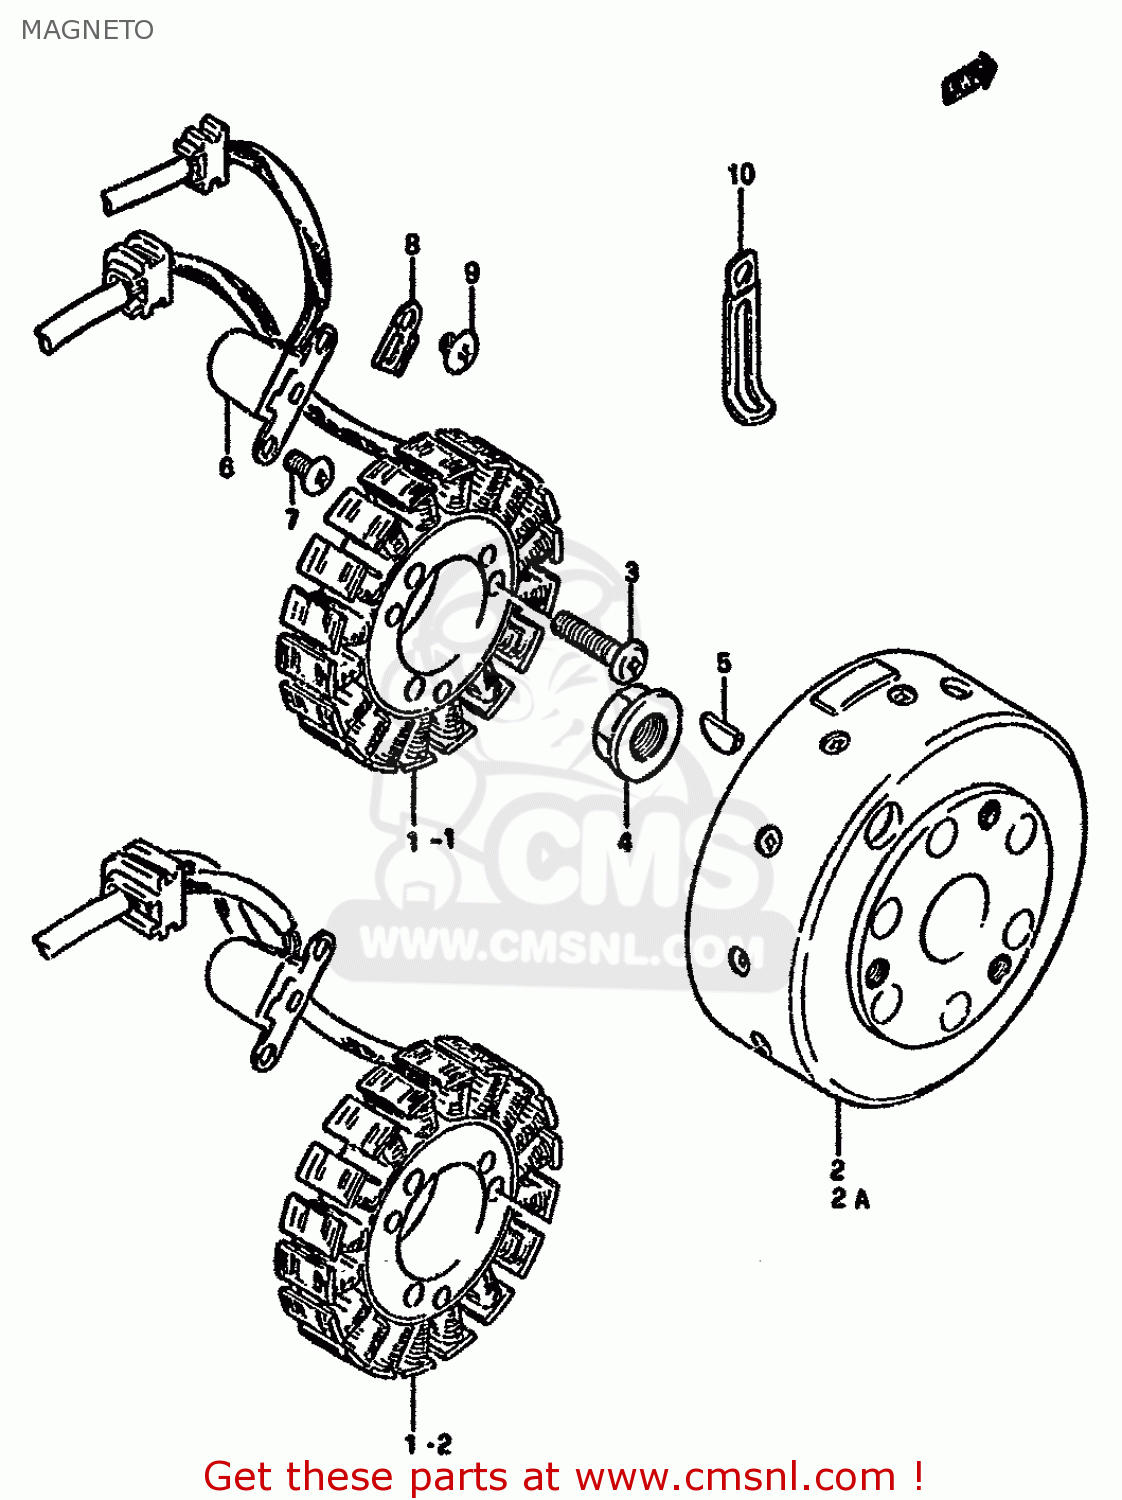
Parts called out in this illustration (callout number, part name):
1	STARTER ASSY
2	ROTOR
2A	ROTOR,FLYWHEEL
3	SCREW
4	NUT,GENERATOR ROTOR
5	KEY
6	COIL ASSY,PICK UP
7	SCREW
8	CLAMP,GENERATOR LEAD WIRE
9	SCREW
10	CLAMP L:35
